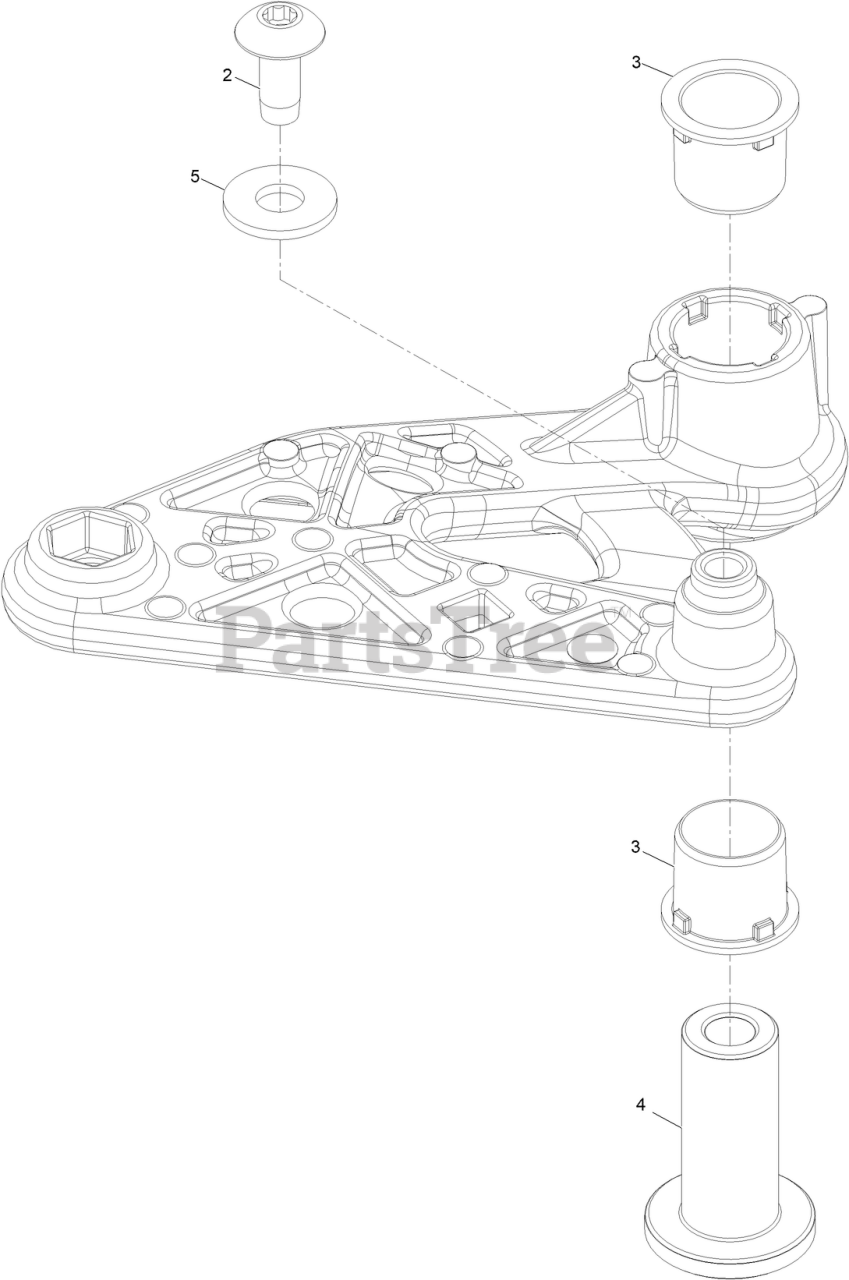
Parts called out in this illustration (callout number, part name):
2	SCREW, TAPTITE
3	BUSHING, IGUS
4	Spacer, Idler Pivot
5	WASHER-FLAT
